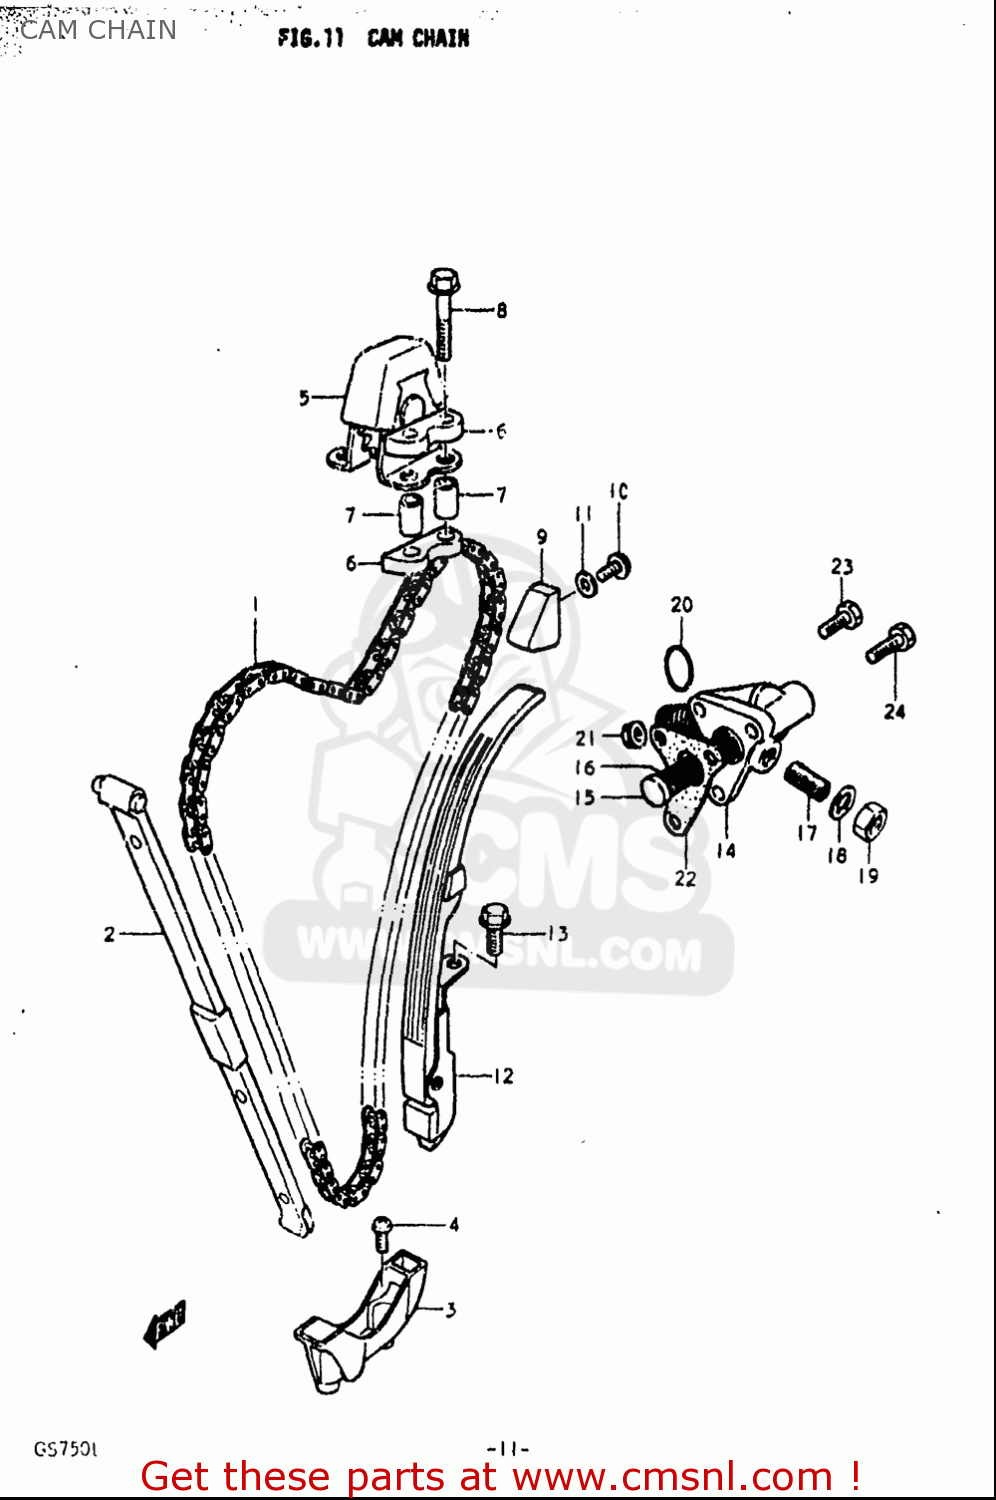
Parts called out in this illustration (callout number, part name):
1	CHAIN,CAMSHAFT DRIVE(120L)
2	GUIDE,CAM CHAIN NO.1
3	HOLDER,CAM CHAIN GUIDE
4	SCREW
5	IDLER,CAM CHAIN
6	CUSHION,IDLER
7	SPACER(6.5X10X13)
8	BOLT
9	GUIDE,CAM CHAIN
10	BOLT
11	GASKET(5.8X13X1.2) (NAS)
12	TENSIONER,CAM CHAIN
13	BOLT
14	ADJUSTER ASSY,TENSIONER
15	ROD,PUSH
16	SPRING
17	SCREW
18	WASHER
19	NUT
20	O RING(D:1.9,ID:5.7)
21	NUT
22	GASKET,TENSIONER ADJUSTER (NAS)
23	SCREW (6X25)
24	SCREW
